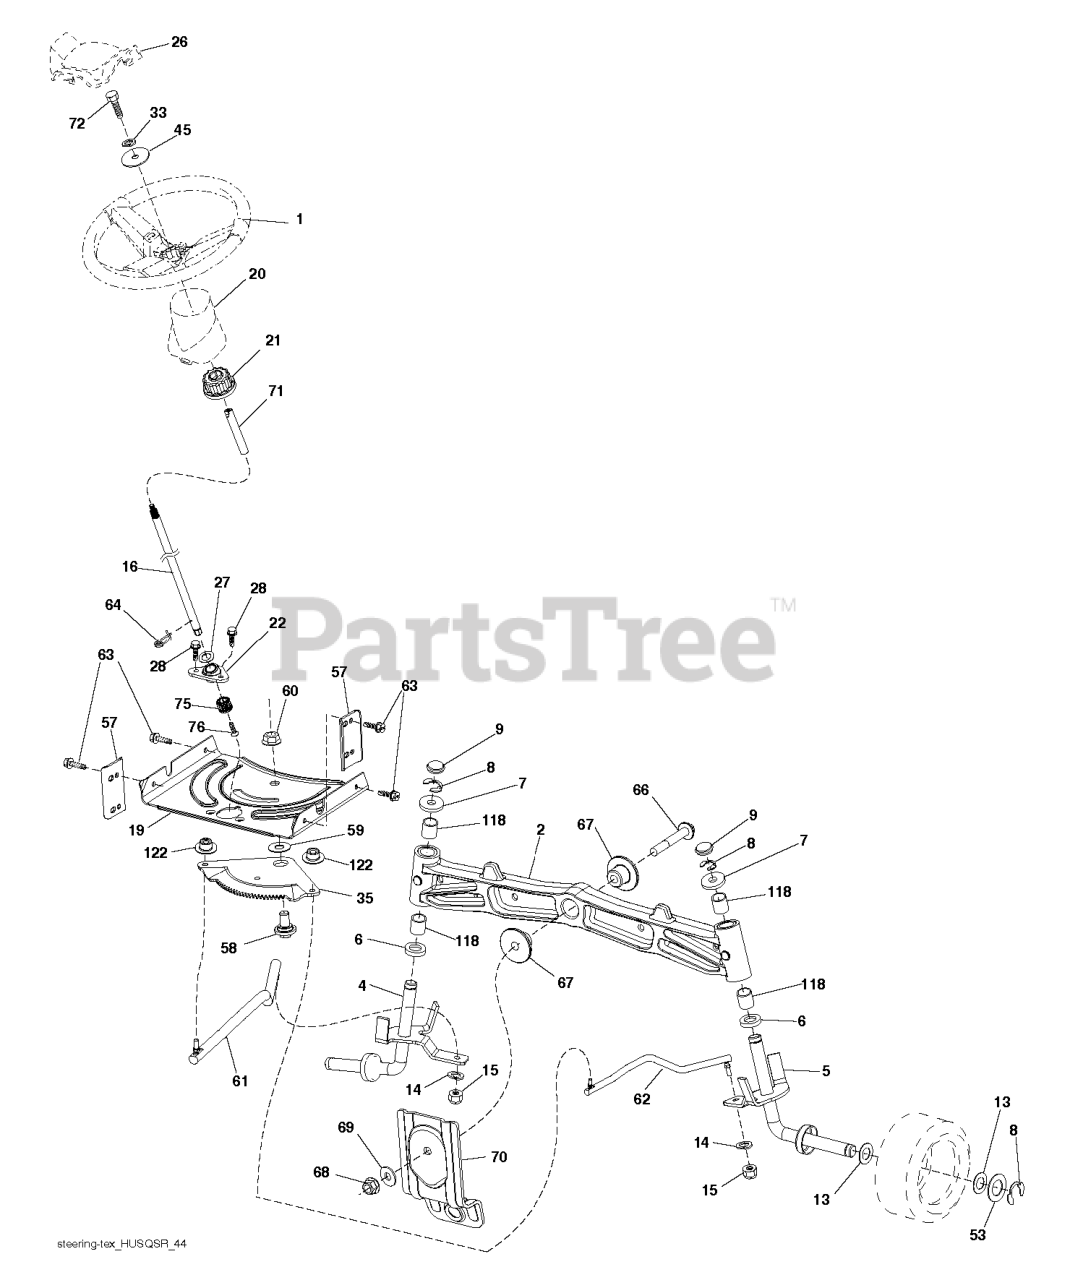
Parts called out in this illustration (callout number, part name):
1	WHEEL.STEER.HUSQ.SR.498.OVMLD
2	AXLE.SVC.ASM CAST IRON.TEX
4	SPINDLE.WELDED.LH.15"TEX
5	SPINDLE.WELDED.RH.15"T
6	THRUST WASHER
9	CAP.SPINDLE.BLACK
14	SLW 3/8 STD
15	NUT CROWNLOCK 3/8-24
16	3 HIGH.SHAFT-ZINC.PLATED
19	PLATE.STEER.DDL.NLT/NG
20	STEERING.BOOT.HUSQ.LT
21	ADAPTER, WHEEL STNG..
22	BEARING.SHAFT.STEER.LOWER.625
26	INSERT.CAP.WHL.STRG.HUSQ.PREM
28	SCREW, 3/8-16X3/4
33	WASHER.LOCK.HVY.HLCL.SPR.5/16
35	GEAR.SECTOR.PLATE.DDL.
45	WASHER.11/32
53	WASHER.HARDENED
57	BRACKET.UPSTOP.TEX
58	BOLT.SHOULDER.SECTOR.P
59	WASHER.THURST.SECTOR.S
60	NUT FLANGE LOCK 5/8-11
61	DRAGLINK.LH.BALLSTUD.D
62	DRAGLINK.RH.BALLSTUD.D
63	SCREW
64	RETAINER.CLIP.SPRING.S
66	BOLT HEX FGHD 7/16-14 X 3 SERR
67	BUSHING.PM.FRONT AXLE
68	NUT.LOCK.FLANGE.7/16
69	WASHER.1.5X.505X.118
70	BRACKET.FRT.DECK.SUSP.RR.MT431
71	SHAFT.EXTEN.STRG.SPLINE
72	BOLT 5/16-18 X 4 W/PATCH
75	PINION.ZINC PLATED
76	SCREW HEAD SOCKET LRVB
118	BUSHING, AXLE CAST
122	CAP.GEAR.SECTOR.TEX
